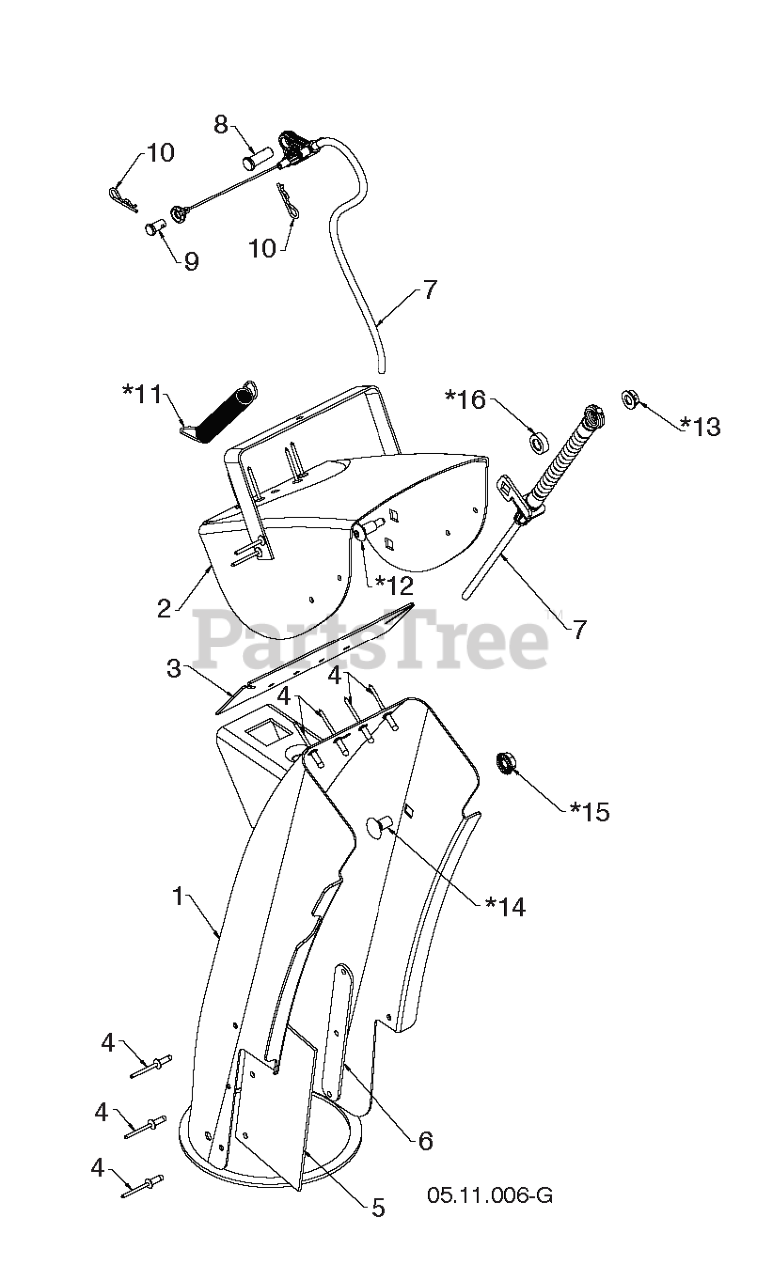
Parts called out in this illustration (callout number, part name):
1	ASM.CHUTE/DEFLECTOR.668
7	CABLE.CONTROL.CHUTE.DEFLEC
8	PIN CLEVIS 5/16X.875
9	PIN CLEVIS .25 X .31
10	HAIRPIN.SOFT.ZINC.059X1.125
16	WASHER.NYLON.326 X.625 X.205
